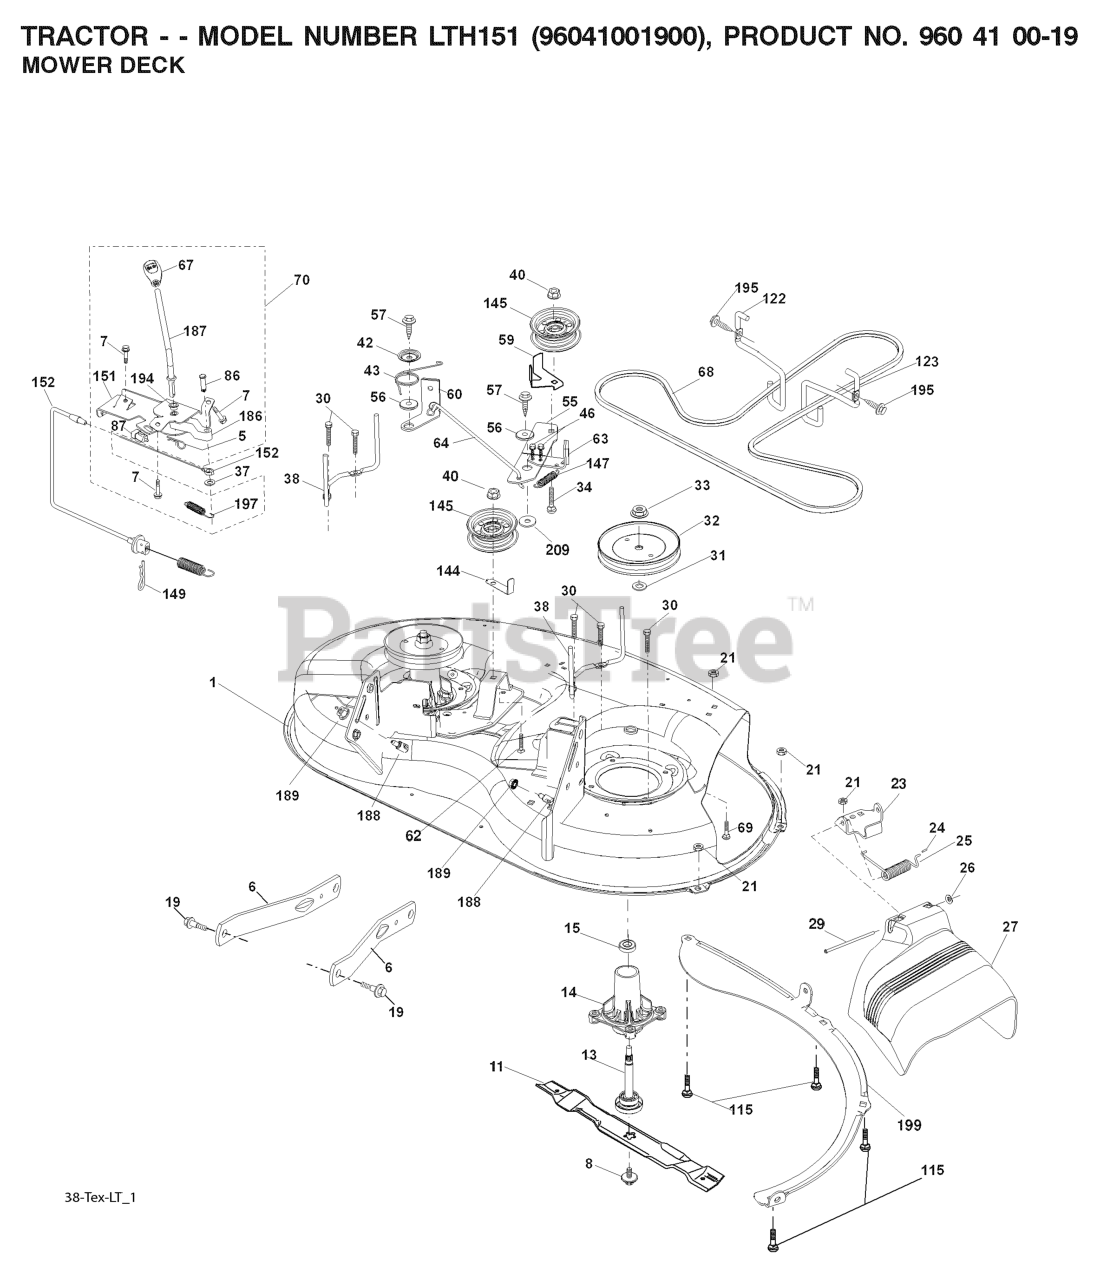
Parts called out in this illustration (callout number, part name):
1	HOUSING
5	RETAINER-SPRNG RB
6	ARM.SUSPENSION.MOWER.R
7	SCREW
8	BOLT.WASHER.ASM.7/16-2
11	BLADE 38" PREMIUM
13	SHAFT.ASM.MDRL.N/GREASE.38
14	RP.HOUSING.MANDREL.4PT.
19	BOLT.SHOULDER
21	LOCKNUT
23	BRKT.DEFLECTOR.38"2005+
24	CAP-SLEEVE LT
25	SPRING.TORSION.DEFLECT
26	NUT PUSH M
27	SHIELD.DEFLECTOR.MWR.38-7/97CM
29	ROD.HINGE
30	SCREW, WASHER HEAD
31	WASHER.SPACER.MANDREL
32	PULLEY.MANDREL.5.0.PD.38"
33	NUT.FLANGE.LOCK.TOP
34	BOLT.3/8-16X1.50
37	WASHER
38	KEEPER BELT LH MANDREL
40	NUT LOCK FLG 3/8-16 UNC
42	SPRING.TORSION.BRAKE
43	SRPING.TORSION.RETAINE
46	SCREW.1/4-20X5/8
56	SPACER.RETAINER
57	SCREW 3/8-16X1
59	GUARD, BELT
60	ARM BRAKE MOWER RH 38"
62	BOLT.3/8-16X1.50
63	RP ARM.BRAKE.MOWER.38"LH.TEX
64	LINK BRAKE
67	HANDLE.CLUTCH.CABLE.LT
69	BOLT
70	CLUTCH.ASM.MANUAL.LT.PRED
86	PIN ATTACHMENT CABLE
87	SWITCH.INTRLCK.CLUTCH.
115	BOLT.CARR.5/16-18X5/8.SHORT
122	KEEPER BELT ENGINE LH
123	KEEPER BELT RH
144	KEEPER, BELT IDLER
145	PULLEY.IDLER.48"PRIMARY
147	SPRING RETURN
149	SPRING.RETAINER.YELLOW.ZINC
151	BRACKET.CLUTCH CBL.PRED LT
152	CLUTCH CABLE
186	ARM ACTUATOR
187	LEVER.CONTROL.CL.CABLE.PRED LT
188	STUD.FASTNER.W/ANTI-ROTATE
189	NUT LOCK HEX FLANGE 5/16-18
194	BEARING.CONTROL.LEVER.CLUTCH
195	SCREW, 3/8-16X3/4
197	SPRING.PLUNGER.ACTUATOR
199	BAFFLE.VORTEX.FRONT.38"
209	WASHER 12/32X2X10GA
